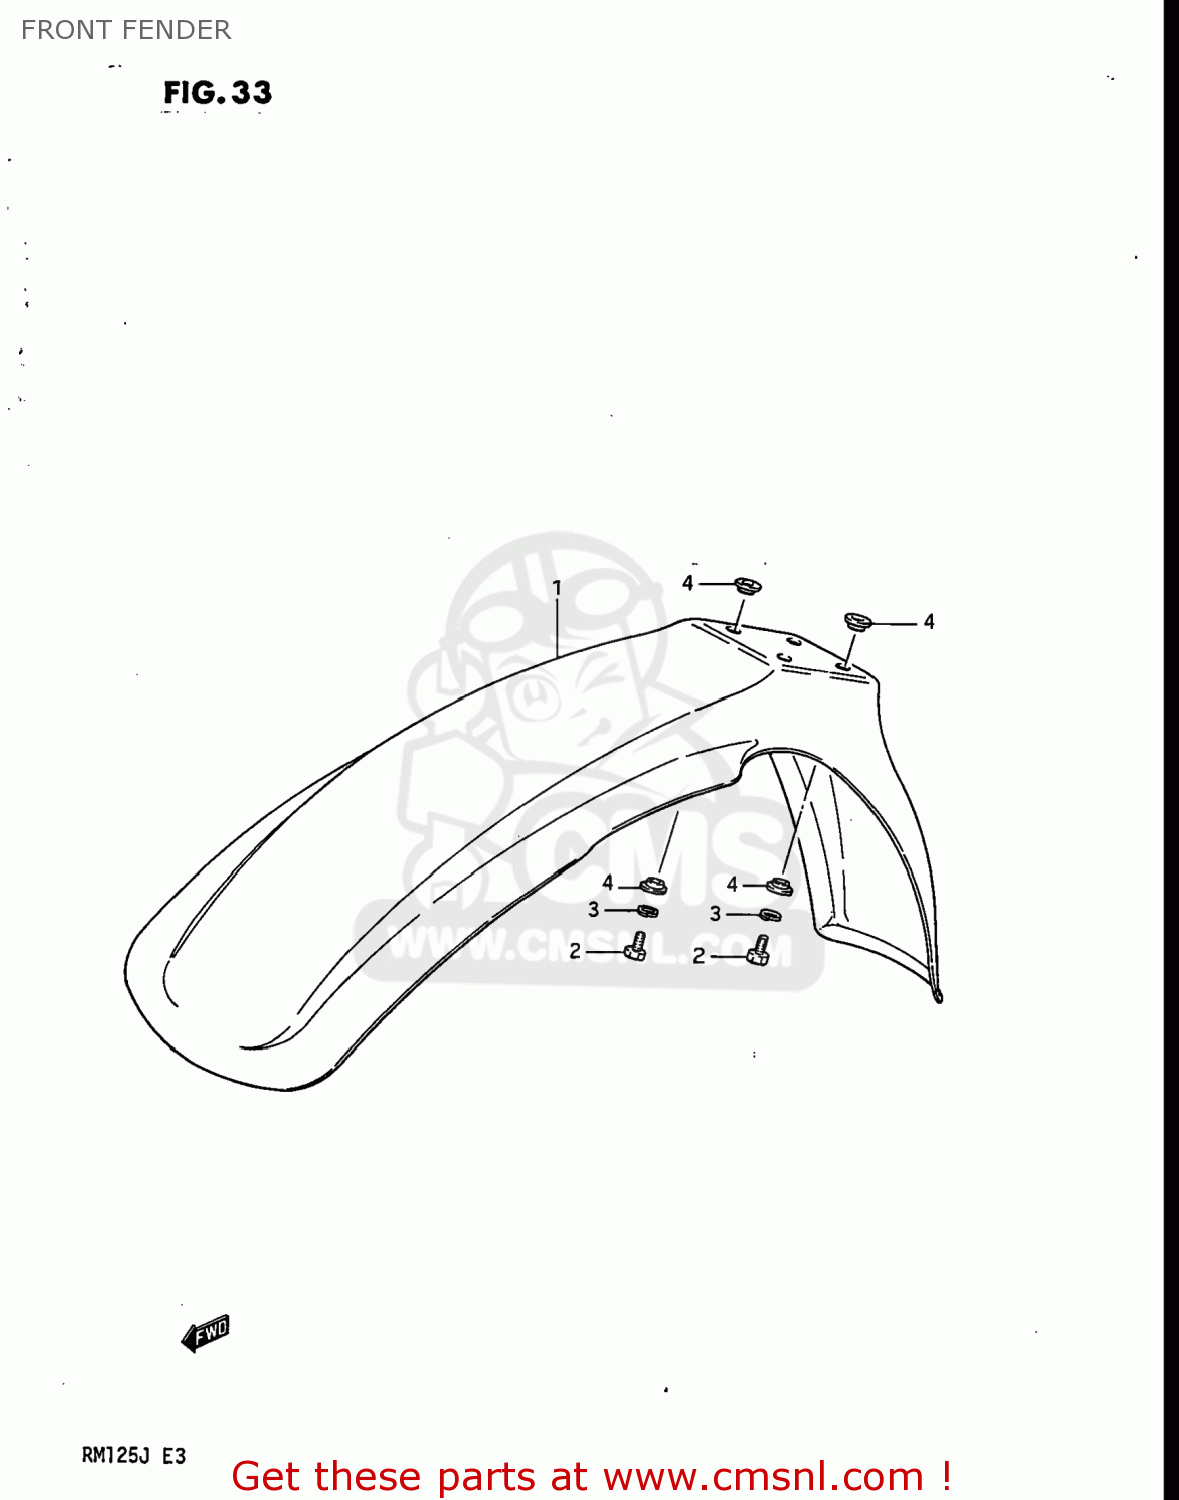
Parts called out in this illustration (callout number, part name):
1	FENDER,FR
2	BOLT
3	WASHER,LOCK
4	WASHER
